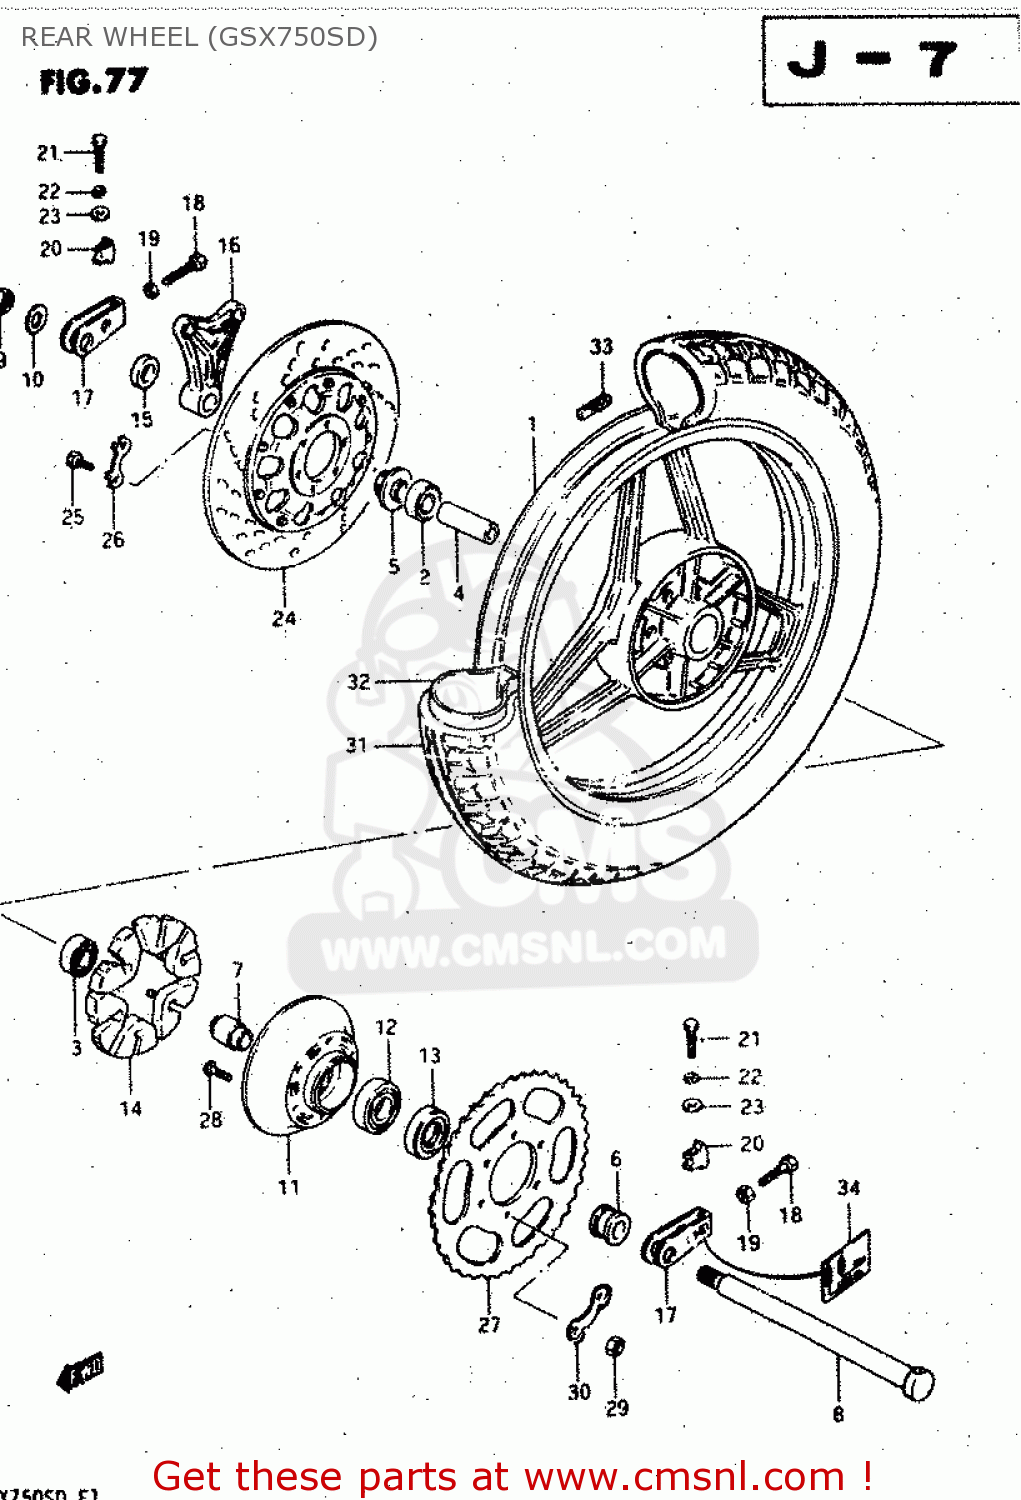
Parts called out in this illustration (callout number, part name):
1	WHEEL, REAR (18X2.15) (BLACK)
2	BEARING WHEEL REAR(20X47X14)
3	BEARING, LH
4	SPACER,REAR HUB BEARING
5	SPACER,REAR AXLE
6	SPACER(20X33X28.3)
7	SPACER,REAR HUB BEARING
8	AXLE,REAR
9	NUT
10	WASHER(19X34X4)
11	DRUM,REAR SPROCKET MOUNT
12	BEARING
13	SEAL,OIL(33X62X7)
14	ABSORBER,REAR HUB SHOCK
15	SPACER (20X38X17)
16	BRACKET,RR,CALIPER
17	ADJUSTER,CHAIN
18	BOLT
19	NUT
20	SUPPORTER,CHAIN ADJUST
21	BOLT
22	LOCK WASHER
23	WASHER
24	DISC,RR BRAKE
25	BOLT(8X30)
26	WASHER
27	SPROCKET,RR
28	BOLT
29	NUT
30	WASHER
31	TIRE
32	TUBE,INNER
33	BALANCER,WHEEL
34	LABEL,CHAIN WEAR INDICATOR
